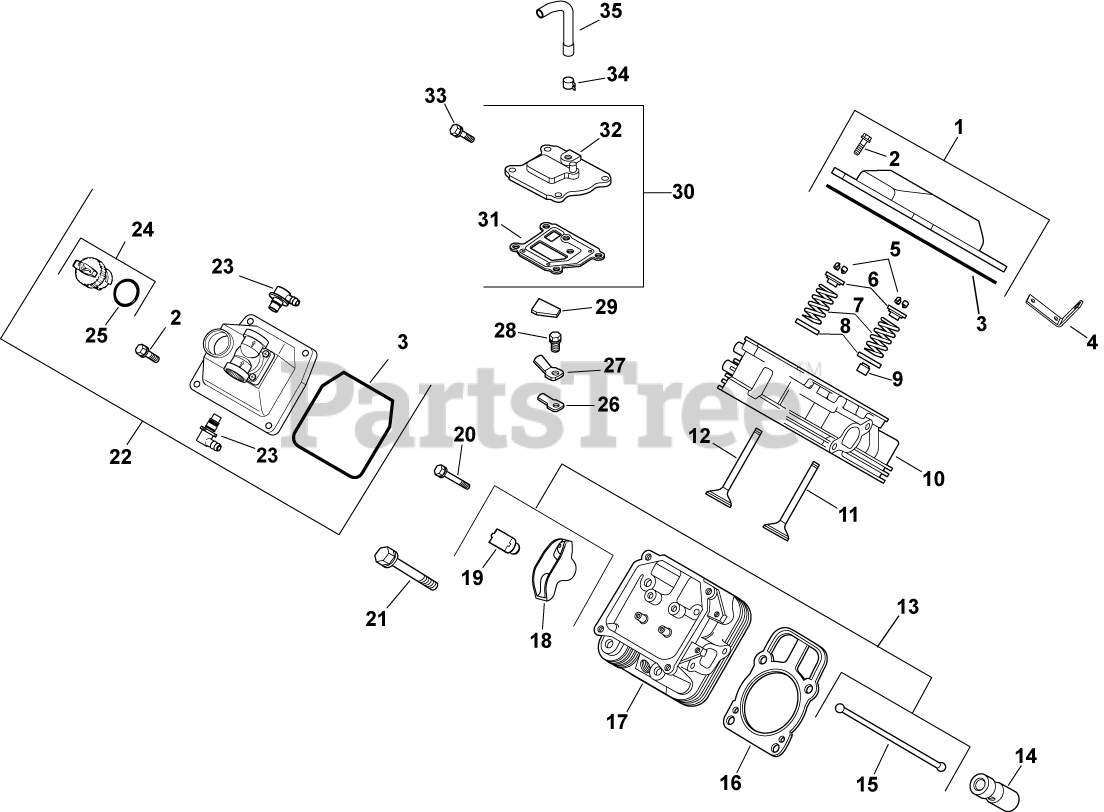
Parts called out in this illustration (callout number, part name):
1	KIT, VALVE COVER-PLAIN
2	SCREW, FLG M6X1.0X30
3	O-RING (YELLOW), VALVE COVER
4	STRAP, LIFTING-USE 25 445 03-S
5	KIT, RETAINER
6	RETAINER, VALVE SPRING - USE 25 173 28-S
7	SPRING, VALVE
8	RETAINER, SPRING
9	SEAL, VALVE STEM - (#2503214S)
10	HEAD, ASSEM CYLINDER #1 -USE 24 318 107-
11	VALVE, INTAKE (STD)
12	VALVE, EXHAUST (STD) - USE 32 016 01-S
13	KIT, VALVE TRAIN
14	LIFTER, HYDRAULIC VALVE-USE 25 351 10-S
15	ROD, PUSH
16	KIT, CYL HEAD GASKET (C17-22)
17	HEAD, ASSEM CYLINDER #2 -USE 24 318 115-
18	ARM, ROCKER
19	PIVOT, ROCKER ARM
20	SCREW, FLG M6X1.0X34
21	SCREW - USE 62 086 08-S
22	KIT, VALVE COVER-FUEL PUMP
23	KIT, 90 DEG. FITTING
24	CAP ASSY, OIL FILL (YELLOW)
25	O-RING-USE 24 153 32-S
26	REED, BREATHER
27	RETAINER, REED
28	SCREW, FLG THD FRM M5X.8X10
29	FILTER, BREATHER
30	KIT, BREATHER ASSEMBLY
31	GASKET, BREATHER-USE 24 041 67-S
32	COVER, BREATHER -USE 24 033 01-S
33	SCREW,FLG THD FRM M6X1.0X20-(#25086396S)
34	CLAMP, HOSE (KM)-USE 25 237 31-S
35	HOSE, BREATHER
2401602-S	VALVE, EXHAUST (.25)
2401702-S	VALVE, INTAKE (.25)
